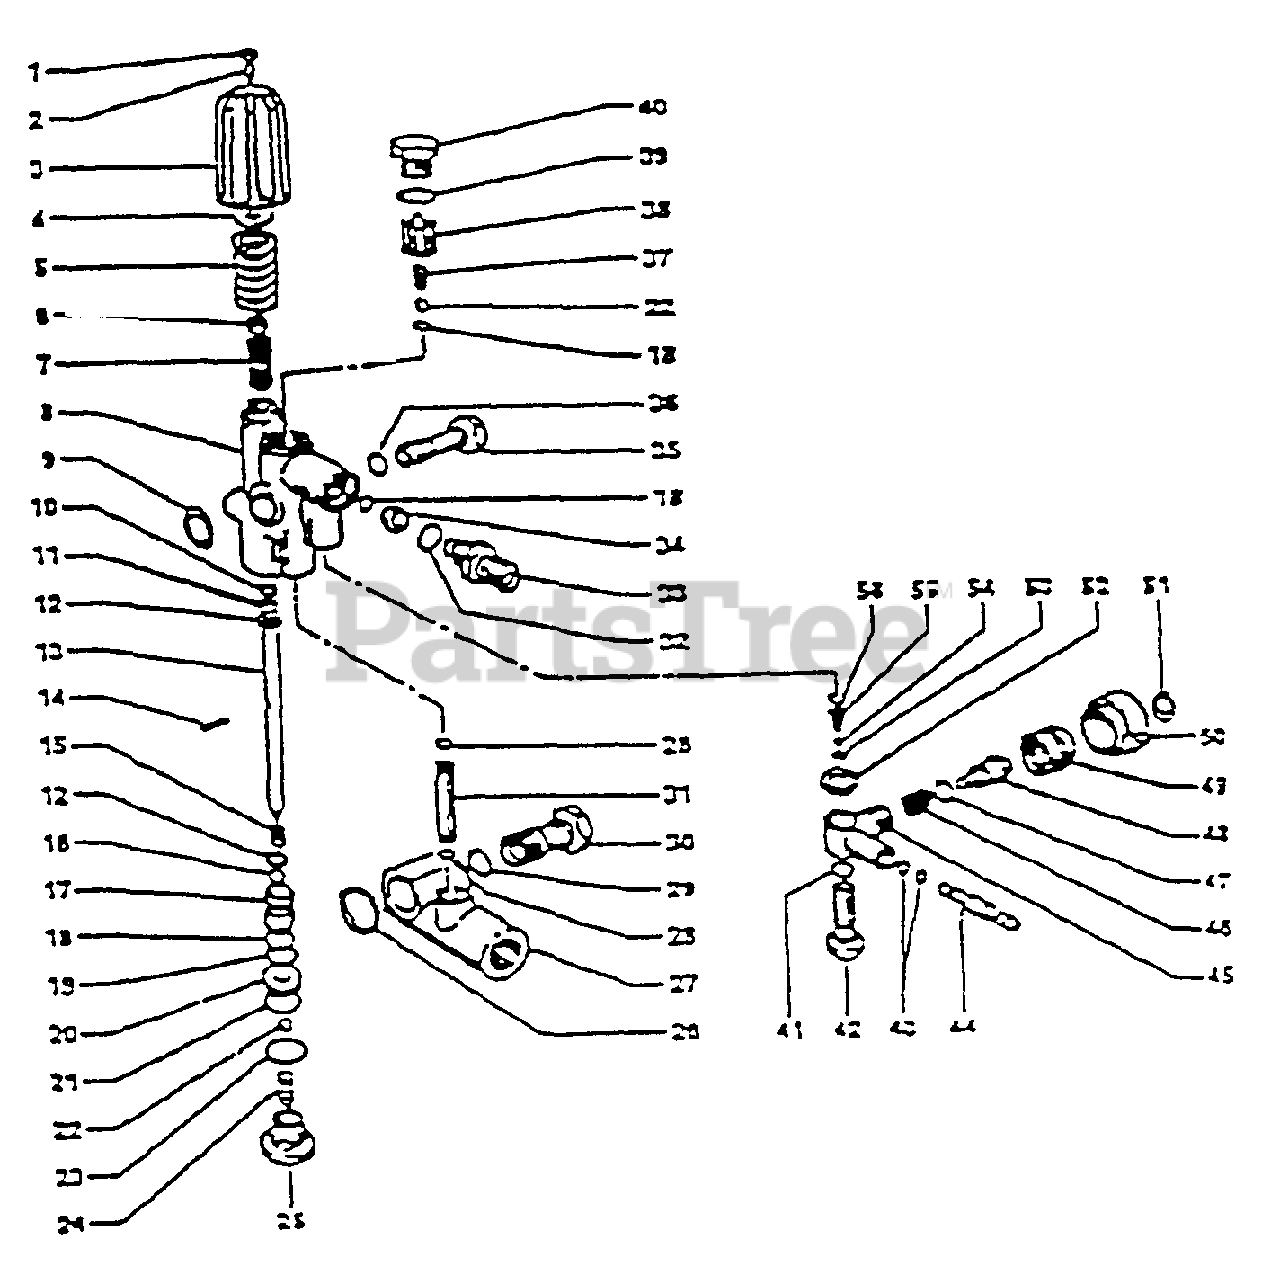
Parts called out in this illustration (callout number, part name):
4	Spring Guide
5	Spring
10	Anti-Ext. Ring
11	O-Ring
13	Piston Guide
15	Spring
16	O-Ring
17	Control Piston
18	O-Ring
19	Anti-Ext. Ring
20	Valve Seat
21	O-Ring
22	Ball
23	O-Ring
24	Spring
27	Banjo Body
28	O-Ring
29	O-Ring
30	Banjo Fitting
31	Bypass Tube; W21
32	O-Ring
34	Nozzle: .087" W21, W21L
36	O-Ring
37	Spring
38	Valve Guide
39	O-Ring
41	O-Ring
42	Valve Seat
43	O-Ring
44	Hose Barb Fitting
45	Injector Body
46	Spring
47	O-Ring
49	Knob Insert
50	Regulation Knob
53	O-Ring
54	Ball
55	Taper Spring
56	O-Ring
